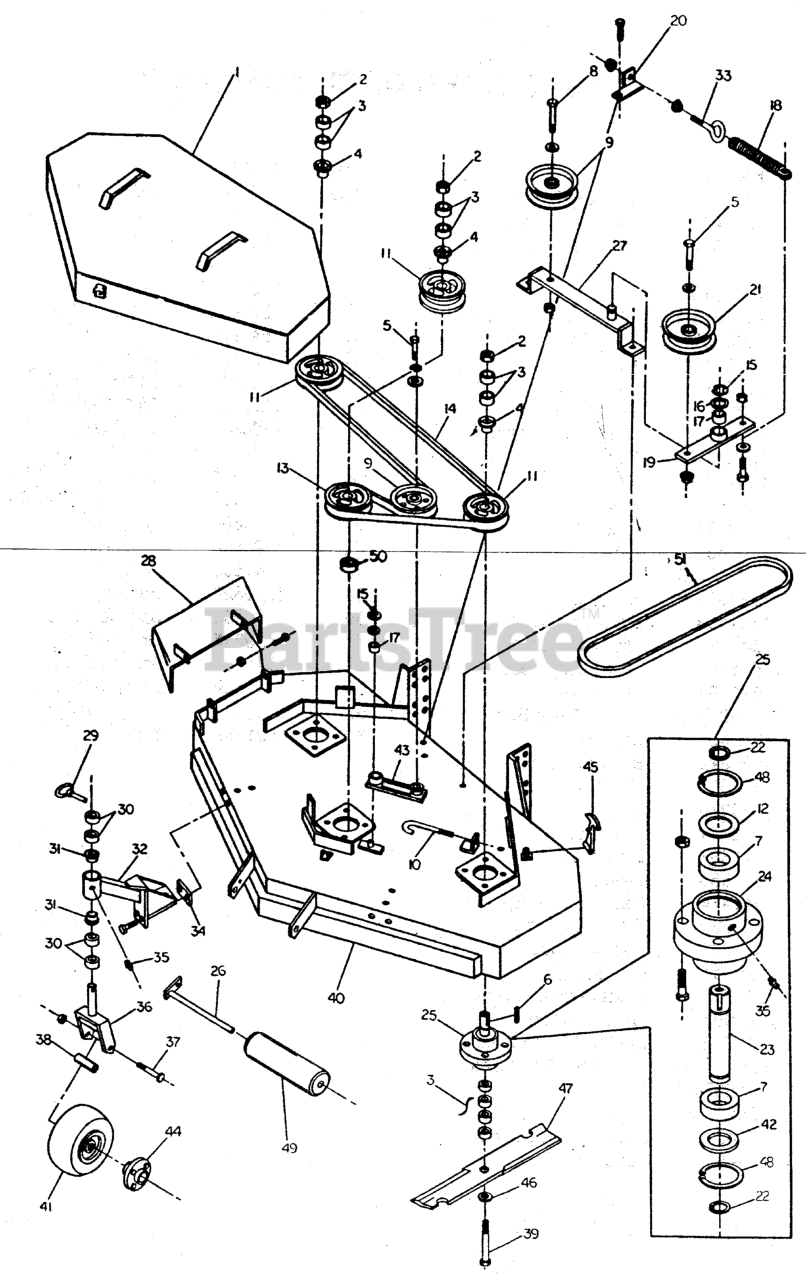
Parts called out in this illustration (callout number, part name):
1	Guard, 52" Deck
2	NUT, 5/8-11 Hex
3	SPACER, .63 x 1.06 x .23
4	BUSHING, Tapered Hub
5	BOLT, 1/2-20 X 2-1/4 GD5 CZ
6	KEY, 1/4 SQ. X 2-1/2
7	BEARING
8	BOLT, 3/8-16 X 3" GD5 CZ
9	PULLEY, Backside Idler
11	PULLEY, Spindle
11	PULLEY, Split Steel
12	SPINDLE WASHER, Top
13	SPINDLE PULLEY
14	BELT, Blade Spindle
15	C-CLIP
16	SHIM
17	BUSHING, Brass
18	SPRING, Extension
19	IDLER ARM, Complete
20	Spring Anchor
21	PULLEY, V-Idler
22	SNAP RING, External
23	SPINDLE SHAFT
24	SPINDLE HOUSING
25	SPINDLE ASSEMBLY, Complete
27	Idler Mount
28	CHUTE, DISCHARGE WELDMENT
29	PIN, Lynch
30	SPACER, 1.02 x 1.56 x .50
31	BUSHING, Flange
32	Caster Support
33	EYEBOLT
34	Caster Mount Spacer
35	GREASE FITTING
36	YOKE, Caster
37	BOLT, 1/2-13 x 5-1/2
38	AXLE, Caster Wheel
39	BOLT, 5/8-11 x 9-1/2
40	52" MOWER HOUSING
41	WHEEL & TIRE ASSEMBLY, White, 9 x 3.5 x 4, Complete
41	TIRE, Front, 9 x 3.5 x 4
41	HUB & BEARING ASSEMBLY, Complete, White
41A	TIRE ASSM, Solid Rubber, 9 X 3.5
42	SPINDLE WASHER, Bottom
43	IDLER ARM
44	Hub (Stamped M)
44	Hub Complete (Stamped T)
45	RUBBER LATCH
46	WASHER, 5/8" USS
47	MOWER BLADE, 18"
48	SNAP RING, Internal
49	ROLLER
50	SPACER, 1.00 X 1.25 X .25
51	BELT, Deck Drive
